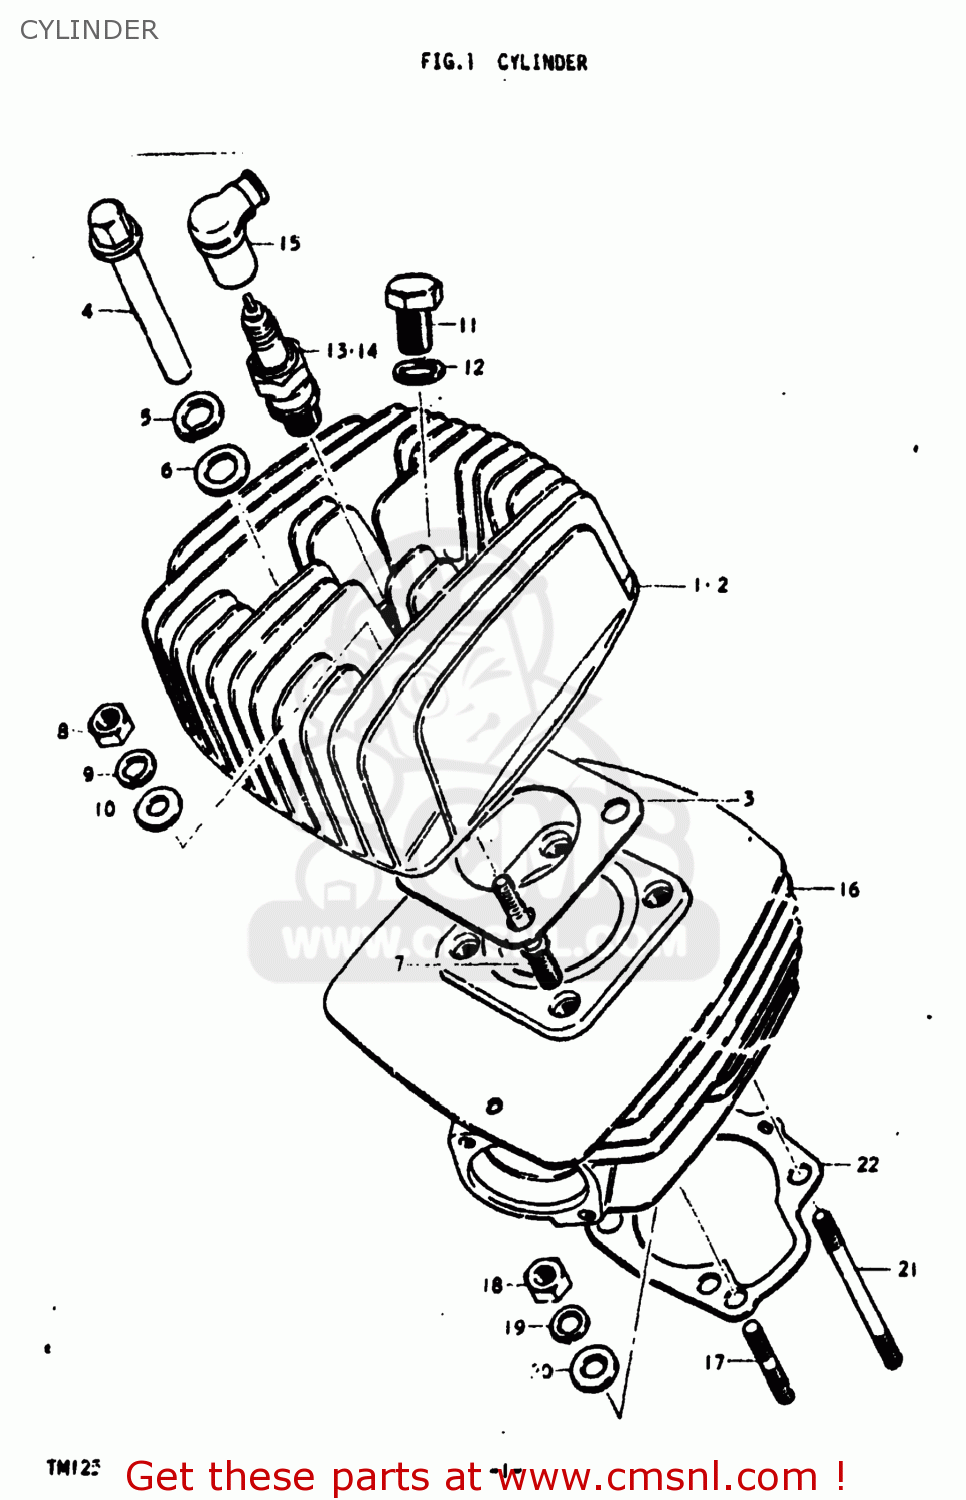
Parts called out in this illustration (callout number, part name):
1	HEAD,CYLINDER
3	GASKET,CYLINDER HEAD (NAS)
4	NUT
5	WASHER,LOCK 12
6	WASHER
7	BOLT,STUD
8	NUT (8MM)
9	LOCK WASHER
10	WASHER
11	PLUG
12	GASKET(14X19.2X2) (NAS)
13	SPARK PLUG
14	SPARK PLUG
15	CAP ASSEMBLY,SPARK PLUG
16	CYLINDER
17	STUD 8X25
18	NUT
19	LOCK WASHER
20	WASHER
21	STUD 8X65
22	GASKET,CYLINDER (MCA)
